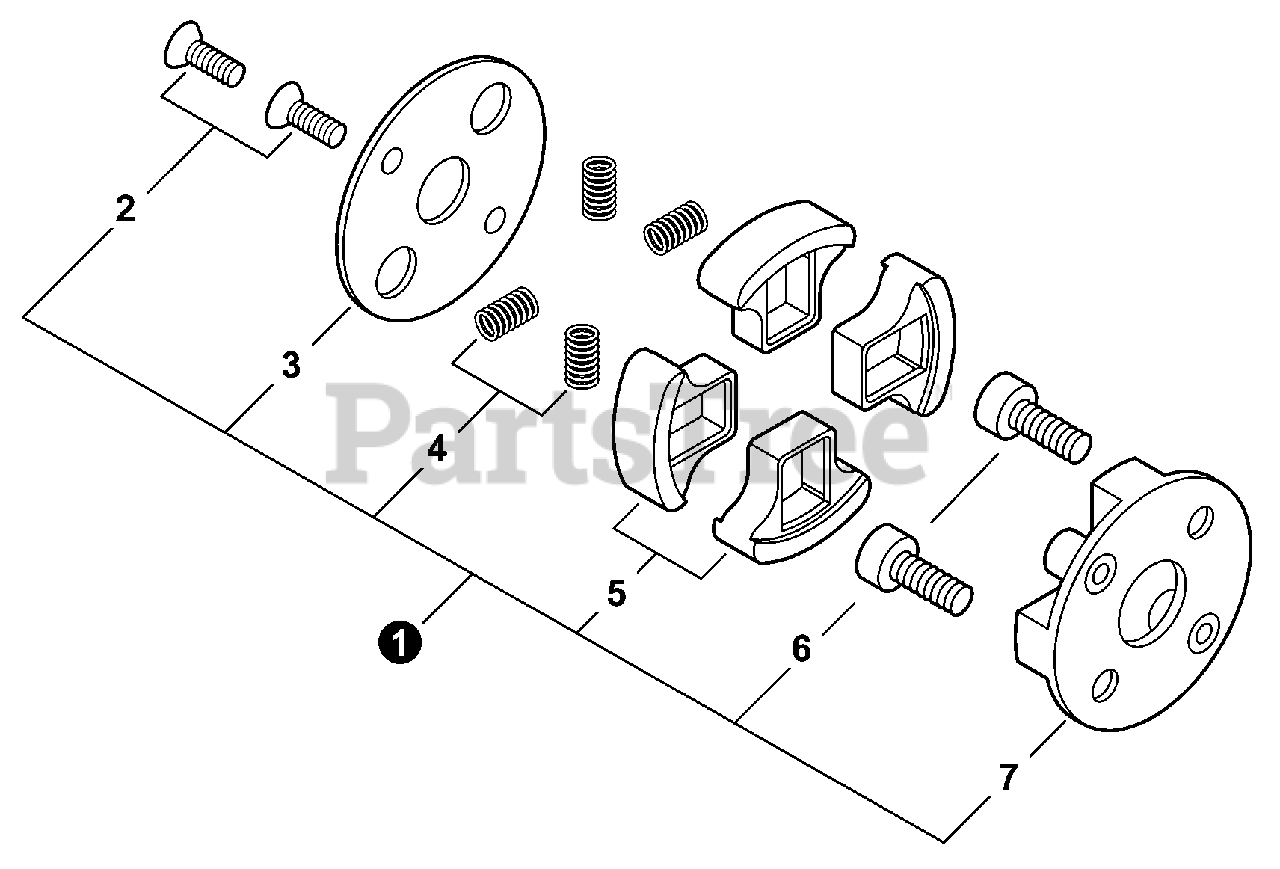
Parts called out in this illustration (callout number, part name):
1	CLUTCH ASSY
3	PLATE, CLUTCH
4	SPRING, CLUTCH
5	SHOE, CLUTCH
6	BOLT, CLUTCH
7	HUB, CLUTCH
